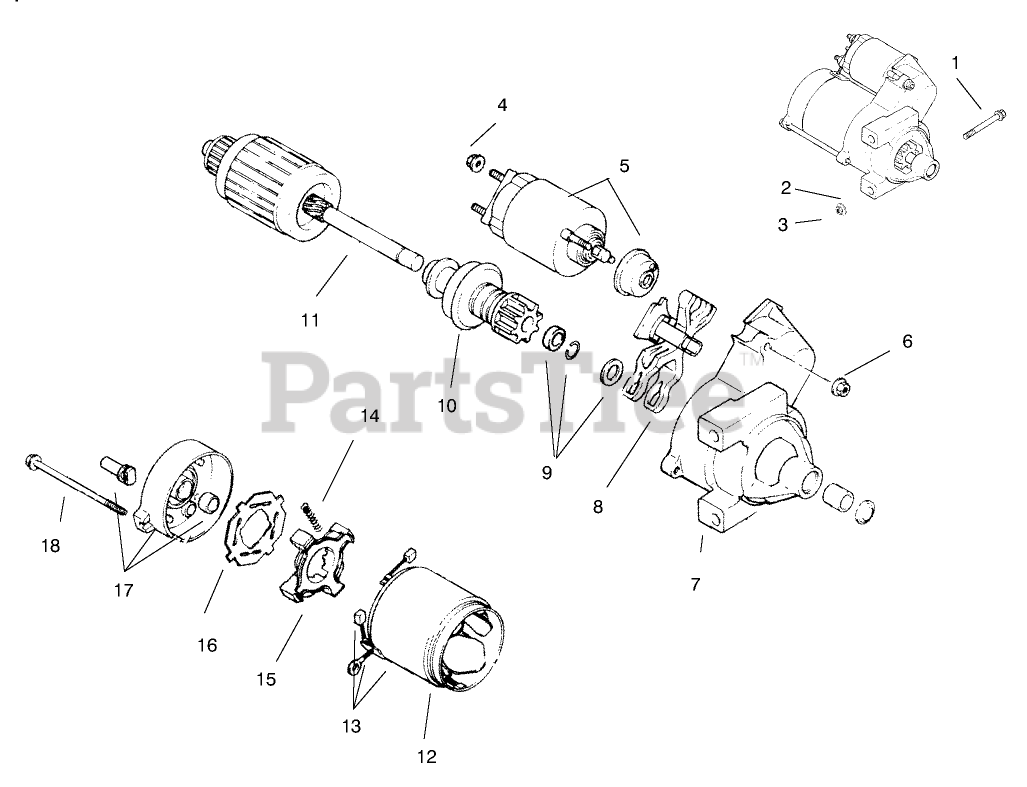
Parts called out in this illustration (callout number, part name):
2	Starter (Incl .Ref.#4-18)
3	Nut
4	Nut
5	Solenoid
6	Nut
7	Cap Drive End
8	Lever Starter Drive
9	Washer
10	Drive Pinion
11	Armature
12	Frame
13	Kit-Brush (Incl. Ref.# 14)
14	Spring Brush
15	Holder-Brush
16	Insulator
17	Cap-Commutator End
18	Bolt
